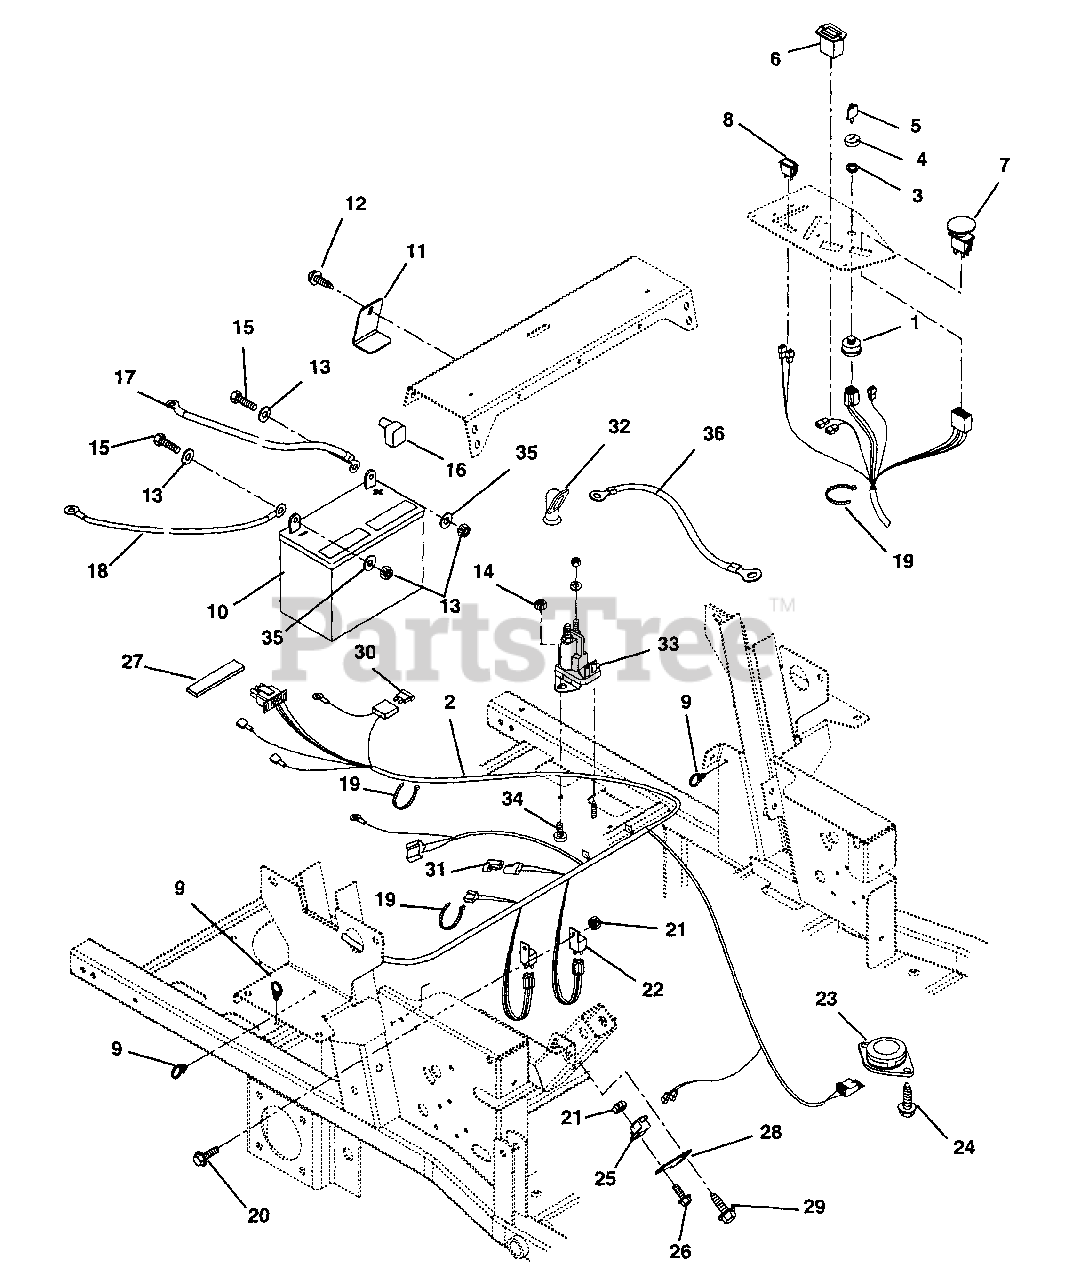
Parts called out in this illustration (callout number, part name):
1	KEY SWITCH
2	HARNESS, Z 6-PIN WIRING
3	NUT- PANEL .562-24 GRECO
4	CAP - IGNITION SWITCH
5	KEY -W/CAP
6	HOUR METER
7	SWITCH, CLUTCH
8	LIGHT,INDICATOR
9	TUBE CLIP 3/4 (4158)
10	BATTERY W/ TUBE
11	CLAMP - BATTERY
12	@SCR-TAP .25-20X.50 HWH TR YWZ
13	@WSHR-FL-STL.281X.62X.065 YWZC
14	@NUT-HEX .25-20 YWZC
15	@BLT-HEX .25-20X.75 GR5 YWZC
16	INSULATOR
17	START CABLE 22"
18	GROUND CABLE .25X13.00X.31
19	CABLE TIE LG 5-1/2
20	@SCR-MCH 10-24X.50 HWH YWZC
21	@NUT-LK-NYL 10-24 W/INSRT YWZC
22	RELAY
23	SEAT SWITCH
24	@SCR-TAP 12-24X.50 HWH TR YWZC
25	SWITCH- SINGLE POLE N.O.
26	@SCR-MCH 10-24X.75 HWH YWZC
27	PAD,BATTERY
28	PLATE - SWITCH
29	@SCR-TAP .38-16X.50 HWH TR YWZ
30	FUSE, 30 AMP.
31	MOLDED DIODE PLUG 1 AMP
32	BOOT, INSULATOR
33	SOLENOID
34	@BLT-HEX .25-20X.50 GR5 YWZC
35	@WSHR-LK .25X.062 REG YWZC
36	STARTER CABLE 6.75"
